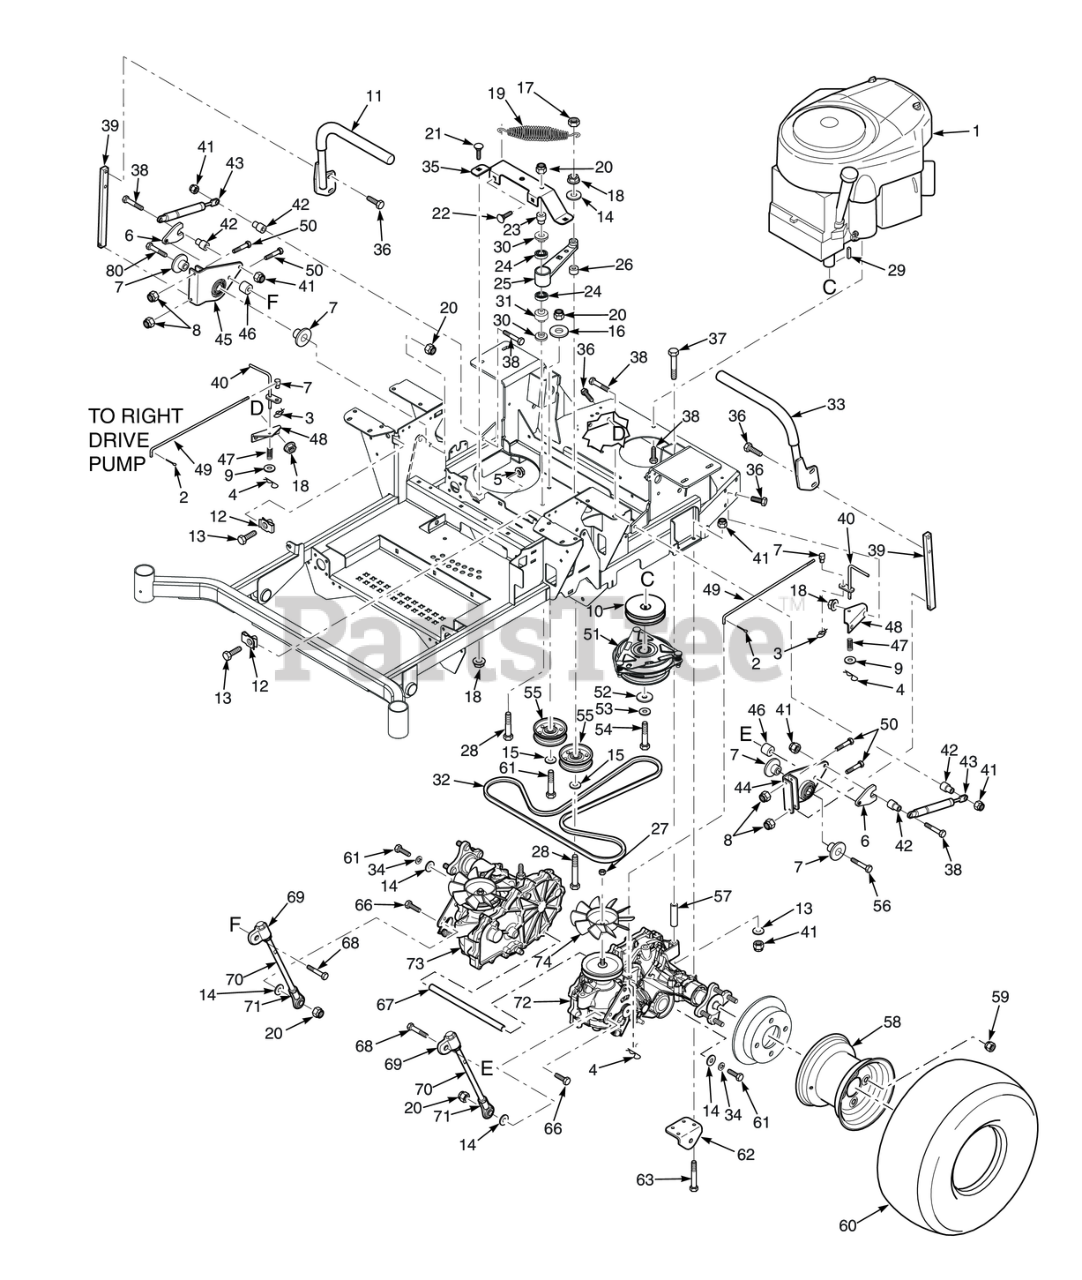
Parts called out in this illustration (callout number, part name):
1	Engine, Kohler - 25CV
2	COTTER PIN, 3/32 X 1"
3	Pin, Rue Cotter 3/8" Diameter
4	HAIR PIN, .08 DIAMETER X 1-3/16"
5	Nut, Serrated Flange 5/16-18 (Right Front Engine Mounting, Briggs and Kohler Only)
6	Nut, Control Linkage
7	Spacer, Linkage
8	HEX, NUT, ELASTIC STOP LOCK, 1/4-20
9	Flatwasher, 1/4" (.312 x .750 x .065")
10	Pulley, 5" OD - 1.125 Bore (SFZ52)
11	Handle Bar Assembly RH, w/Grip
12	U-Nut, 3/8-16 (short)
13	Bolt, Hex Head 3/8-16 x 1-1/4" Special Lock
14	Flatwasher, 3/8" Special (.391 x .938 x .105)
15	Flatwasher, 3/8 (.391 x .938 x .105 HD) Grade 8
16	Flatwasher, 3/8-.406 x 1-1-1/2 x 7 Gauge
17	Bolt, Hex Head 3/8-16 x 1" Ser. Flg.
18	NUT, 3/8-16 SERRATED FLANGE HEX HEAD
19	Spring, Transmission Idler
20	HEX NUT, ELASTIC STOP LOCK, 3/8-16
21	Bolt, Carriage 3/8-16 x 3/4"
22	Bolt, 5/16-18 x .75 RHSN Carriage
23	Shaft Pivot, Idler Arm
24	BEARINGS, BALL, NEUTRAL RETURN
25	Trans. Idler Arm Assy. (Includes 24, 79)
26	Spacer, Idler Pulley - SFZ61
27	Fan Nut (order through Hydro-Gear)
28	Capscrew, Hex Head 3/8-16 x 3.25"
29	Key, 1/4" x 1/4" x 2-3/4" Pulley Mtg.
30	Spacer, Controls
31	Spacer, Bearing
32	Belt, Transmission Drive - SFZ61
33	Handle Bar Assembly LH, w/Grip
34	Lockwasher, 3/8" Spring, Kawasaki FX / FS
35	Support, Idler Arm
36	Capscrew, 3/8-16 x 1.0" Serrated Flange Hex Hd
37	HEX HEAD BOLT, 5/16-18 X 5"
38	Bolt, Hex Head 5/16-18 x 1-1/2" (Right Front Engine Mounting, Briggs and Kohler Only)
39	Bar, Control Lever
40	Dump Valve Lever
41	HEX NUT, ELASTIC STOP LOCK, 5/16-18
42	Spacer, Pump Dampener
43	Gas Damper
44	Control Link, LH
45	Control Link, RH
46	Spacer, Idler Pulley - SFZ52
47	Spring, Dump Valve Link
48	Bracket, Dump Mounting
49	Rod, Brake Adjustment
50	Bolt, Hex Head, 1/4-20 x 1-1/2"
51	Electric Clutch Assembly - SFZ52 & SFZ61
52	Flatwasher, 7/16-.469 x 1.75 x .25 (48, 52)
53	Lockwasher, 7/16� Spring
54	Bolt, Hex Head 7/16-20 x 1-1/2" Patch SFZ-61
55	Pulley, 3-1/2" Dia.
56	Capscrew, Hex Head 3/8-16 x 2.0"
57	Spacer, Axle - SFZ61
58	(52") Rim 481851 (61") Rim w/Stem
58	Rim w/Valve Stem, (Black) - SPZ61
59	Wheel Nut, 1/2-20 x 13/16
60	Wheel Assembly, 24 x 12-12 (SPZ61)
61	Capscrew, Hex Head 3/8-16 x 2-1/2"
62	Bracket, Push Arm Link
63	Bolt, Hex Head 5/16-18 x 3.00"
64	Clip, Brake Lever (order through Hydro-Gear)
65	Lever, Brake (order through Hydro-Gear)
66	Bolt, Hex Head, 3/8-16 x 1-1/2"
67	Spacer, Axles
68	Capscrew, Hex Head 3/8-16 x 2.0"
69	Rod End, Adjustable 3/8-24
70	Linkage, Pump - SFZ61
71	Stake, Rod End Assembly
72	Transaxle Assy., LH (ZY-GCEE-SL7F-11TX)
73	Transaxle Assy., RH (ZY-KCEE-SL7G-11TX)
74	Fan (order through Hydro-Gear)
